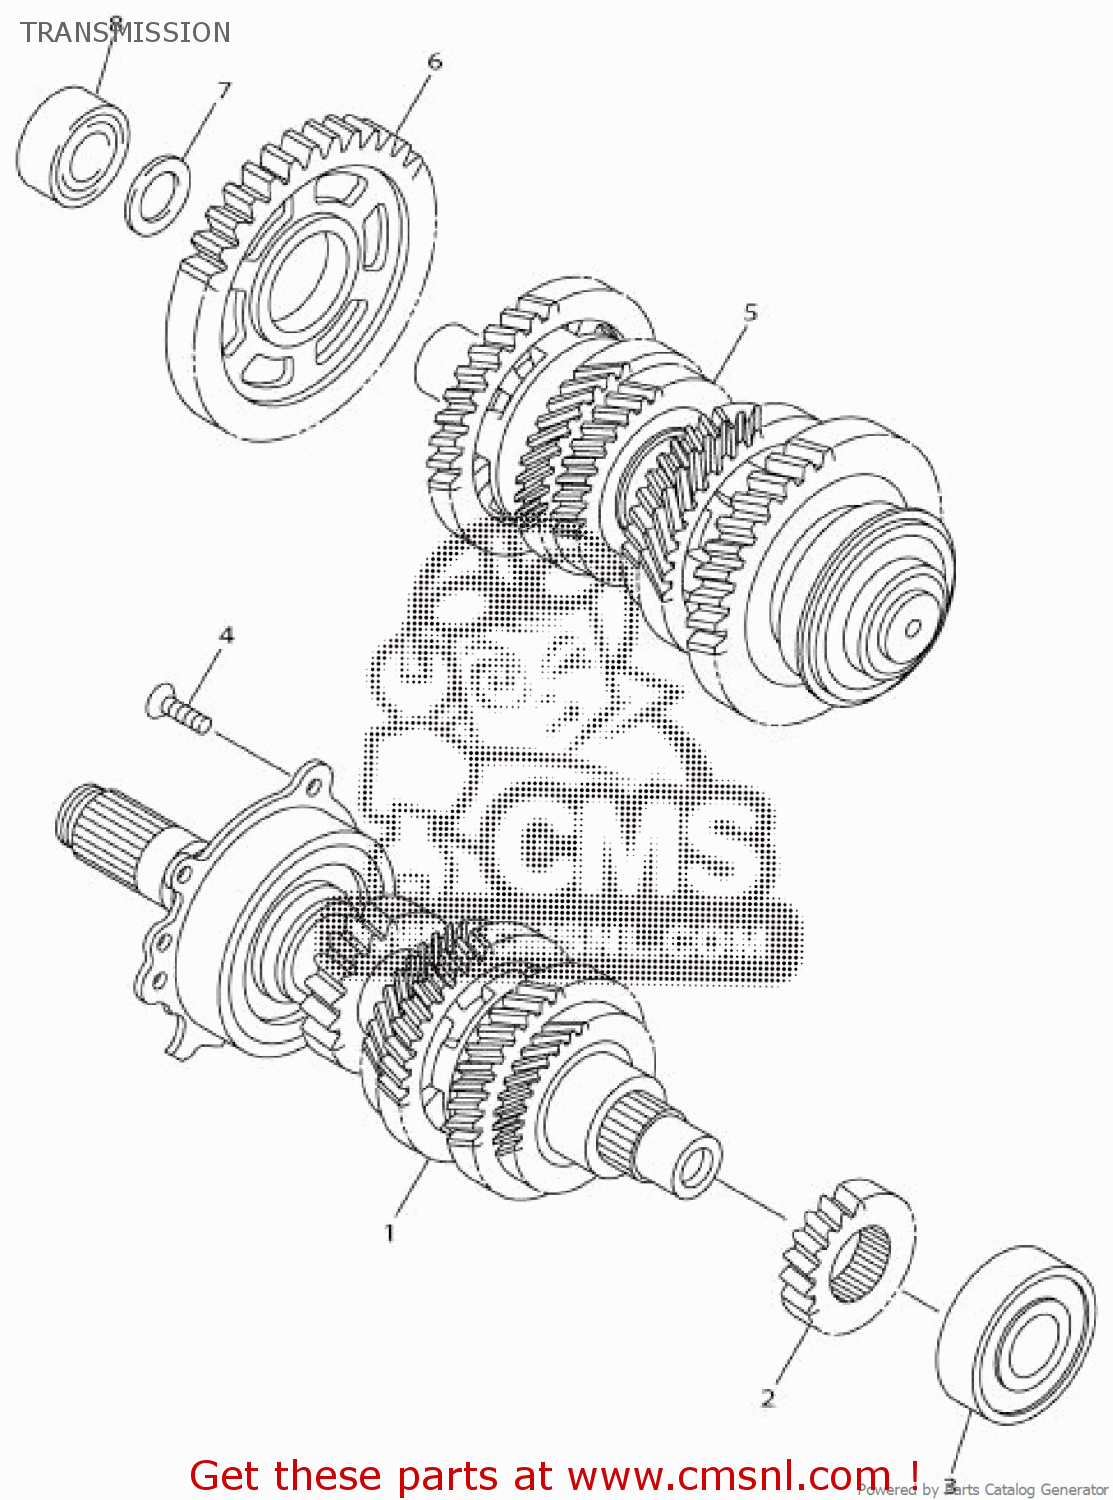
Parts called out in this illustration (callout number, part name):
1	MAIN AXLE COMP.
2	GEAR,1ST PINION
3	BEARING
4	SCREW
5	DRIVE AXLE ASSY
6	GEAR, MIDDLE DRIVE
7	WASHER, PLATE
8	BEARING
